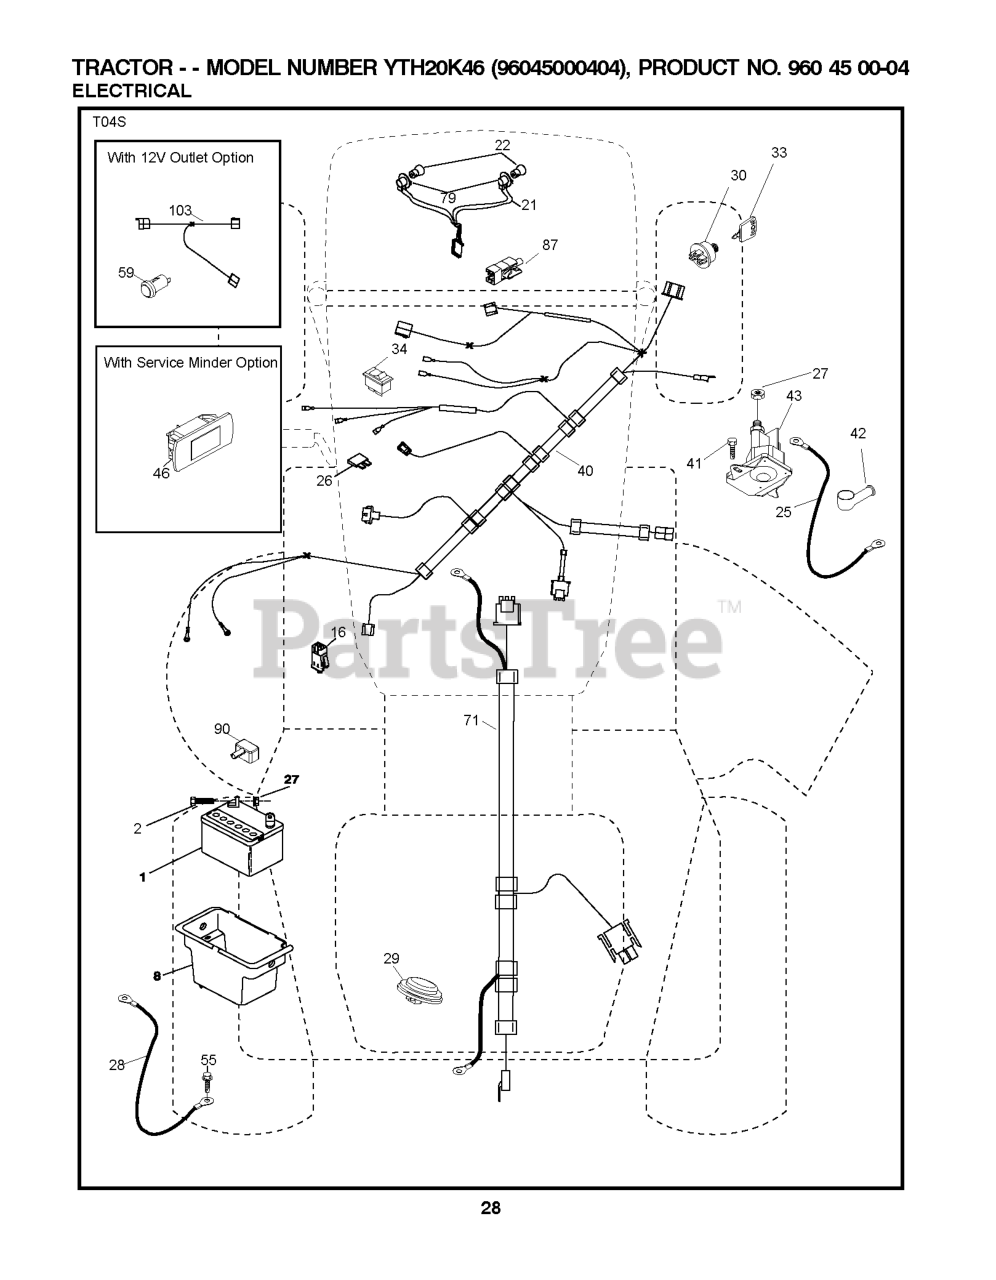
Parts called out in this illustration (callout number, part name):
1	Battery 12 Volt 25 Amp
2	BOLT.HEX.1/4.X.3/4.DICHROMATE
8	BOX.BATTERY.MNT.REAR.L
16	SWITCH INTERLOOK PUSH-IN
21	HARNESS ASSY LIGHT
25	CABLE.STARTER.6G.BL/RED.17.5
26	FUSE 20AMP
27	NUT
28	CABLE.BLACK.18"REAR.BA
29	SWITCH.SEAT.DELTA.OPC.
30	SWITCH.IGN.DELTA.W.LGH.ROS
33	KEY.CHAIN.BLISTER.PACK.GEN.USA
40	HARNESS.IGN.CHASS.TEX.REAR.BAT
41	SCREW
42	TERMINAL COVER
43	SOLENOID.W/BRASS.PLUNGER
46	RP.GUAGE.SRVCMNDR.HRMTR.
55	SCREW 5/16"
71	HARNESS IGN. DASH
79	BULB HOLDER ASM.
87	SWITCH.INTRLCK.CLUTCH.
90	COVER, TERMINAL BATTERY
